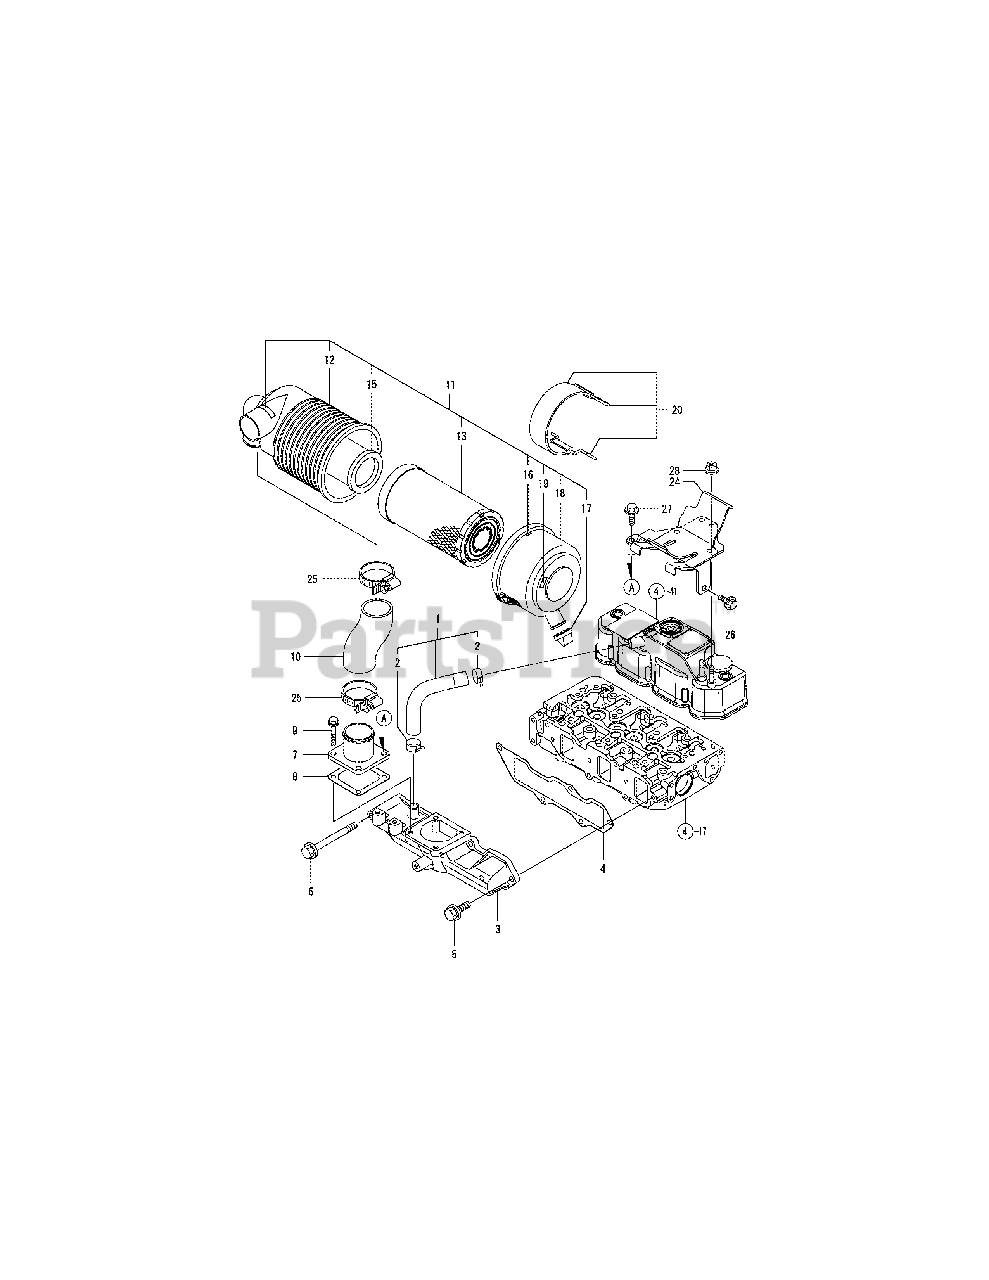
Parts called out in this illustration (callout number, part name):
1	PIPE, BREATHER
3	MANIFOLD, AIR INTAKE
4	GASKET,INT. MANIFOLD
5	BOLT M 8X 20 PLATED
6	BOLT M 8X 80 PLATED
8	GASKET, (NON-ASB.)
9	BOLT M 8X 20 PLATED
11	CLEANER ASSY, AIR
12	CLEANER, AIR
13	ELEMENT, OUTER
15	ELEMENT, INNER
17	VALVE, UNLOADER
24	SUPPORT, CLEANER
26	BOLT M 8X 12 PLATED
27	BOLT M 8X 50 PLATED
